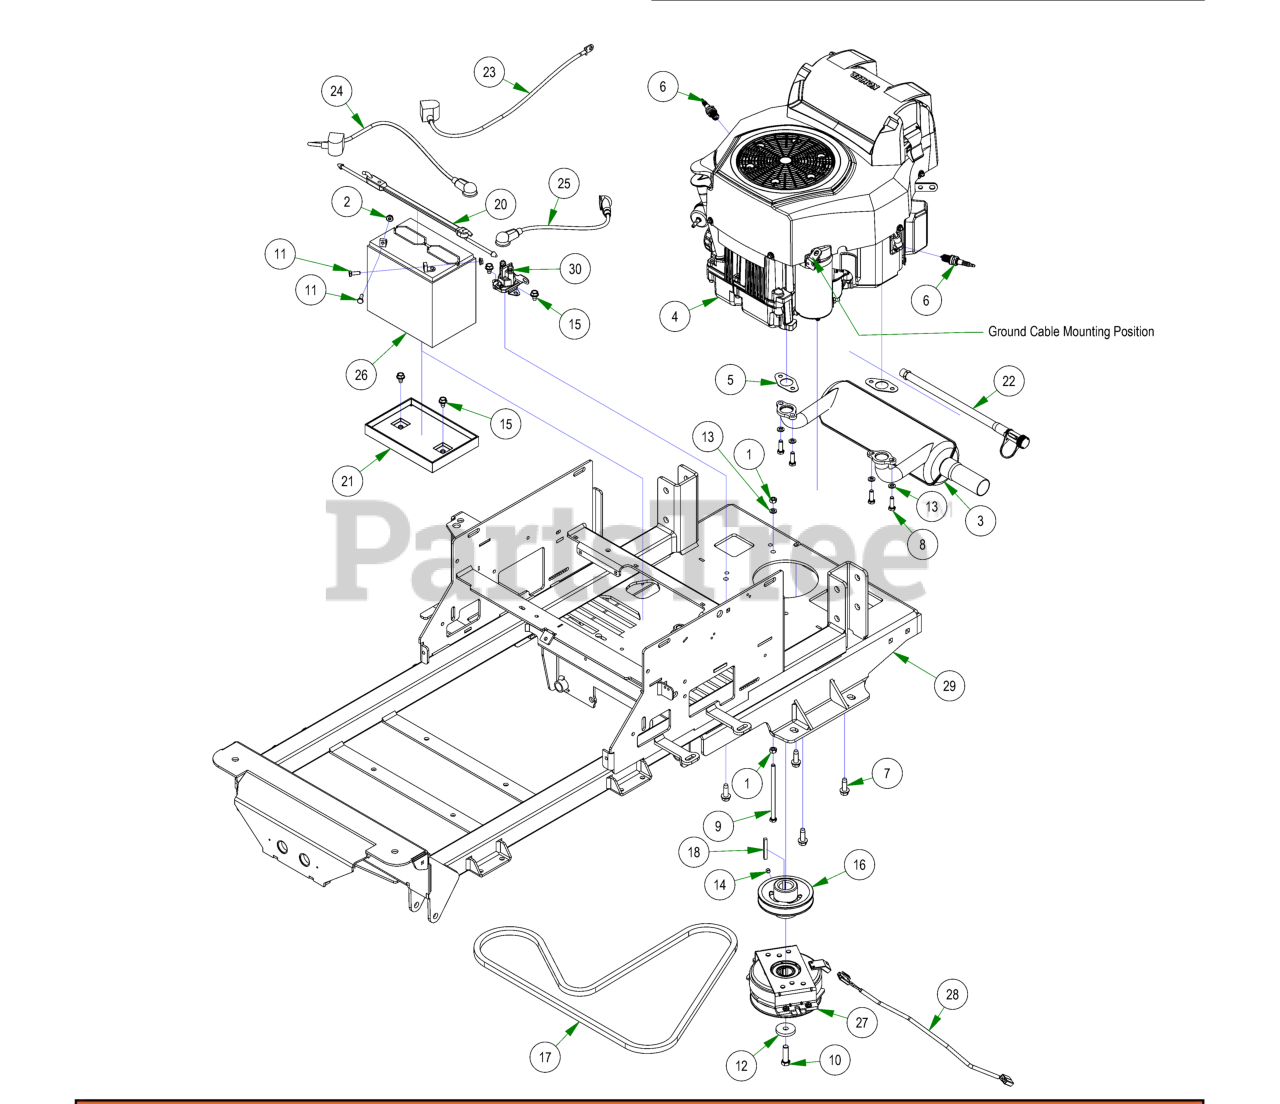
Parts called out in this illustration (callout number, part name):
1	5/16-18 HEX NUT ZINC
2	1/4-20 HEX SERRATED FLANGE NUT HARD/ZINC
3	Kohler Muffler
4	Kohler-2014 CZT/Outlaw 747cc
5	Exhaust Gasket
6	Spark Plug
7	3/8-16 X 1-1/8 HEX WASHER UNSLOT SERRATED (TRI-LOB) TRS ZINC YELLOW
8	5/16-18 X 1 HEX CAP SCREW (GR.5) ZINC
9	5/16-18 X 5-1/2 HEX CAP SCREW (GR.5) ZINC
10	7/16-20 X 1-1/2 HEX CAP SCREW (GR.8) w/ Patch
11	1/4-20 X 3/4 HEX CAP SCREW (GR.5) ZINC
12	CLUTCH WASHER
13	5/16 SPLIT LOCKWASHER ZINC
14	5/16-24 X 1/4 SOCKET SET SCREW (CUP PT) PLAIN
15	5/16-18 X 1/2 HWH unslot (F) tcs zinc
16	4 3/4 Motor Pulley
17	75.8" Pump Belt
18	1/4 X 2 SQ MACHINERY KEY 1018 STL PLAIN
19	2023 Battery Hold Down Assembly
20	2023 Rubber Battery Hold Down Strap
21	Battery Tray
22	Kohler Oil Drain
23	24 inch Black Cable – MZ/ZT
24	24" Red Battery Cable
25	12" Red Battery Cable
26	SP-35 Battery
28	Clutch Pigtail
29	2023 Maverick Frame - Painted
